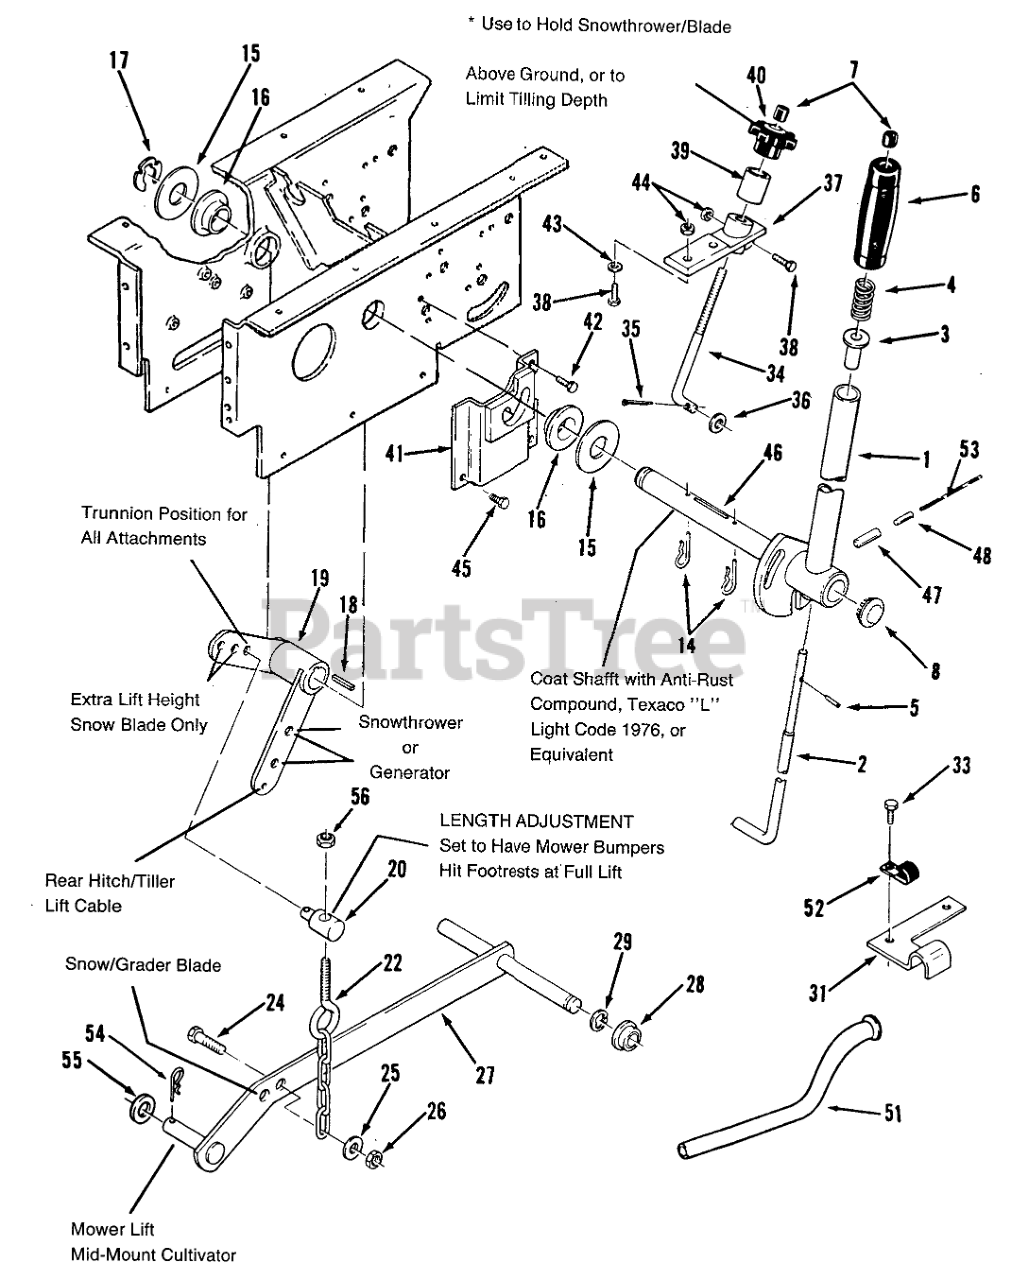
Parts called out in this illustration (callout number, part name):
1	Lift lever
2	Pin-Cotter
3	WASHER
4	BEARING-FLANGE
5	Retainer
6	KEY-SQUARE
7	Bellcrank
8	TRUNNION-LIFT
9	Hairpin Cotter
10	CHAIN-LIFT
11	Bolt
12	WASHER 5/16 SAE
13	Nut
14	ASSY LIFT BAR R
15	BUSHING
16	E Ring
17	CLAMP-CONDUIT R
18	BOLT
19	TUBE-CONDUIT R
20	CLIP
21	Hairpin Cotter
22	Washer
23	NUT
